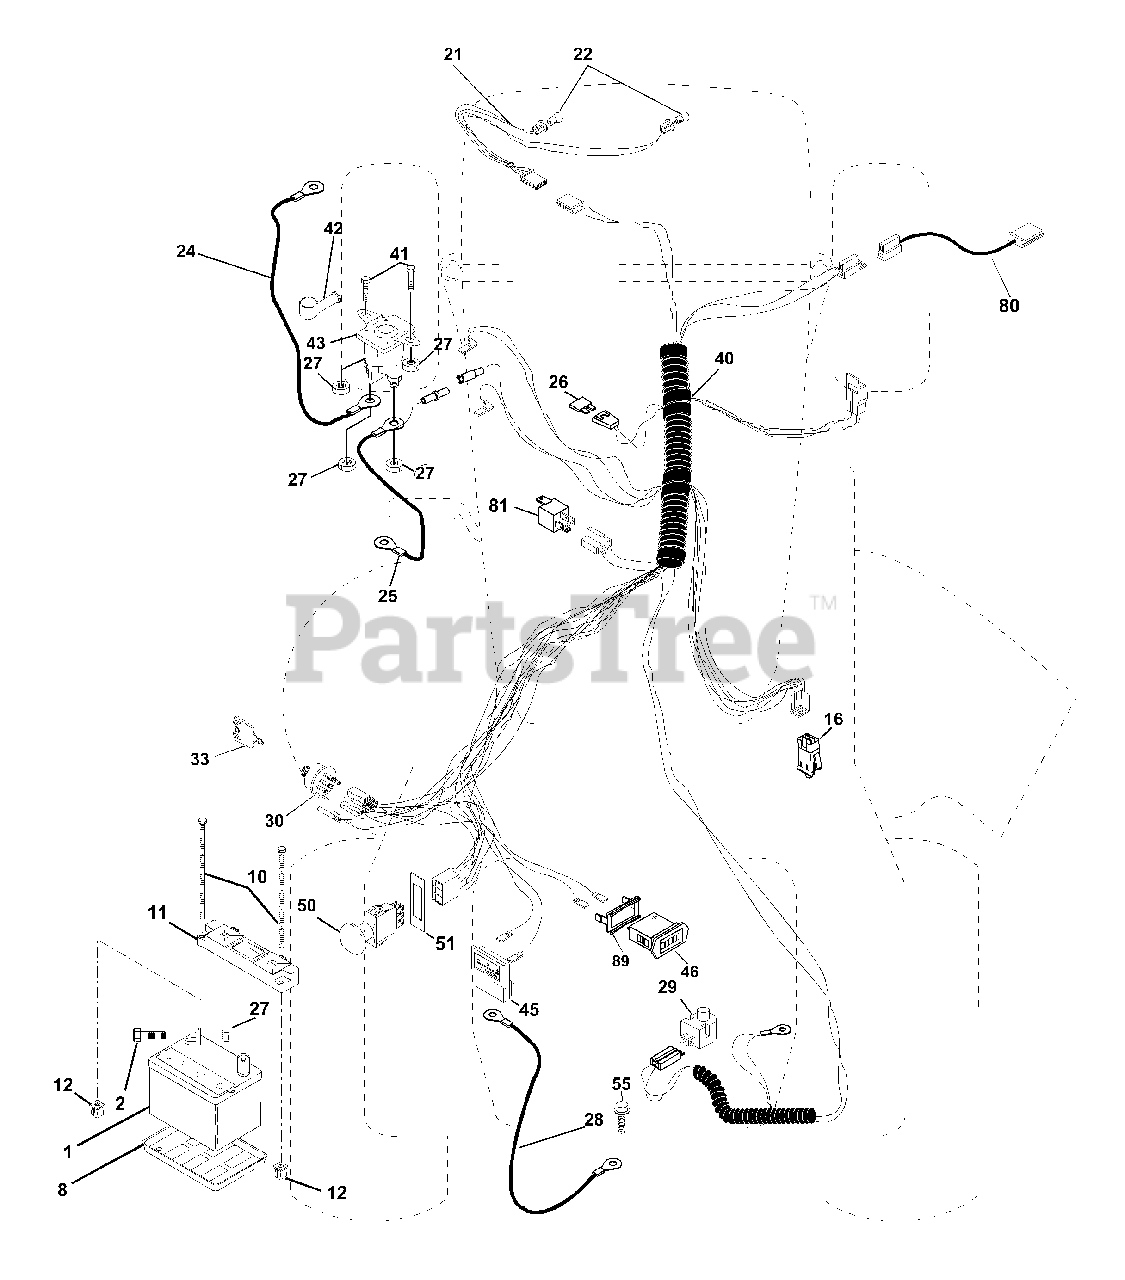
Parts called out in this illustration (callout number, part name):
1	Battery, 12 Volt, 35 Amp
2	Bolt, Hex Head 1/4-20 UNC x 3/4
8	Tray, Battery
10	Bolt, Battery Front 1/4-20 x 7.5 Zinc
11	Holddown Battery Dash Mount
12	Nut, Push Nylon 1/4" Battery Front
16	Switch Interlock Push-In
21	Harness, Light
22	Bulb, Light
24	Cable, Battery, 6 Gauge, 11", Red
25	Cable, Battery
26	Fuse, 15 Amp
27	Nut, Hex, Keps 1/4-20 UNC
28	Cable, Ground, 6 Gauge, 12", Black
29	Switch, Plunger, Normal Op Olive
30	Switch, Ignition
33	Key, Ignition
40	Harness, Ignition
41	Bolt, Hex, Fin. 1/4-20 x 1/2
42	Cover, Terminal, Red
43	Solenoid
45	Ammeter, Rectangular, 15 AMP
46	Hourmeter Snap-In
50	Switch, PTO
51	Ring, Retainer, PTO
55	Screw, Thdrol 5/16-18 x 1/2 TYT
80	Harness Clutch EVX
81	Relay Assembly
89	Bracket Snap-In Hourmeter
